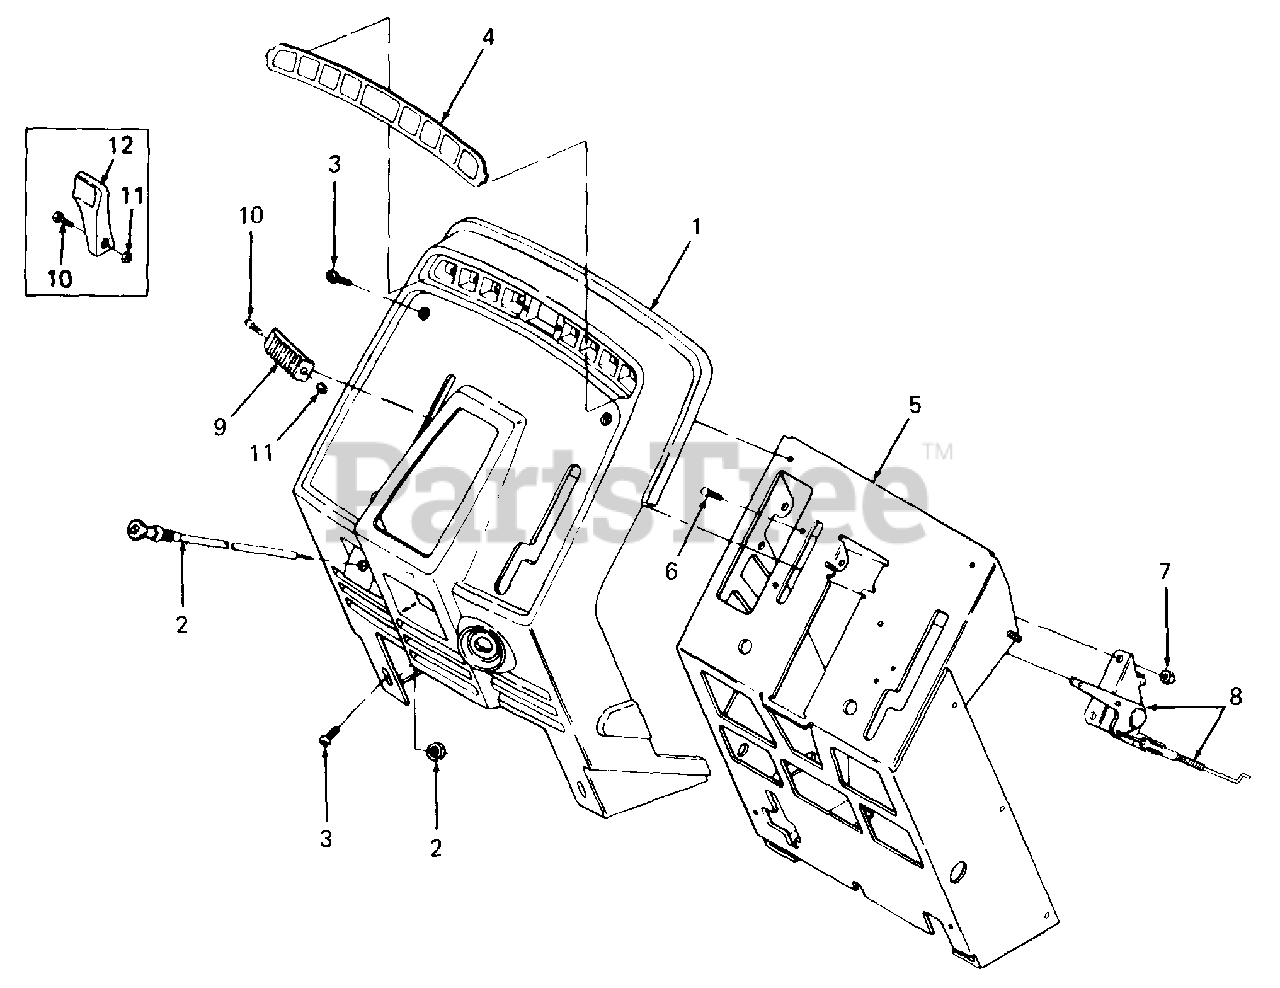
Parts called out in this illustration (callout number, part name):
1	Panel, Instrument
2	Choke Cable w/Nut
3	Screw, Pan Hd Cutting, #10-24 X .75 Lg
4	Label, Dash
7	Nut, Hex Keps, #10-32
8	Control, Throttle
9	Knob, Throttle
10	Screw, Cross Rec Truss Hd, #8-32 X .38 Lg
11	Nut, 8-32
12	Knob, Throttle
